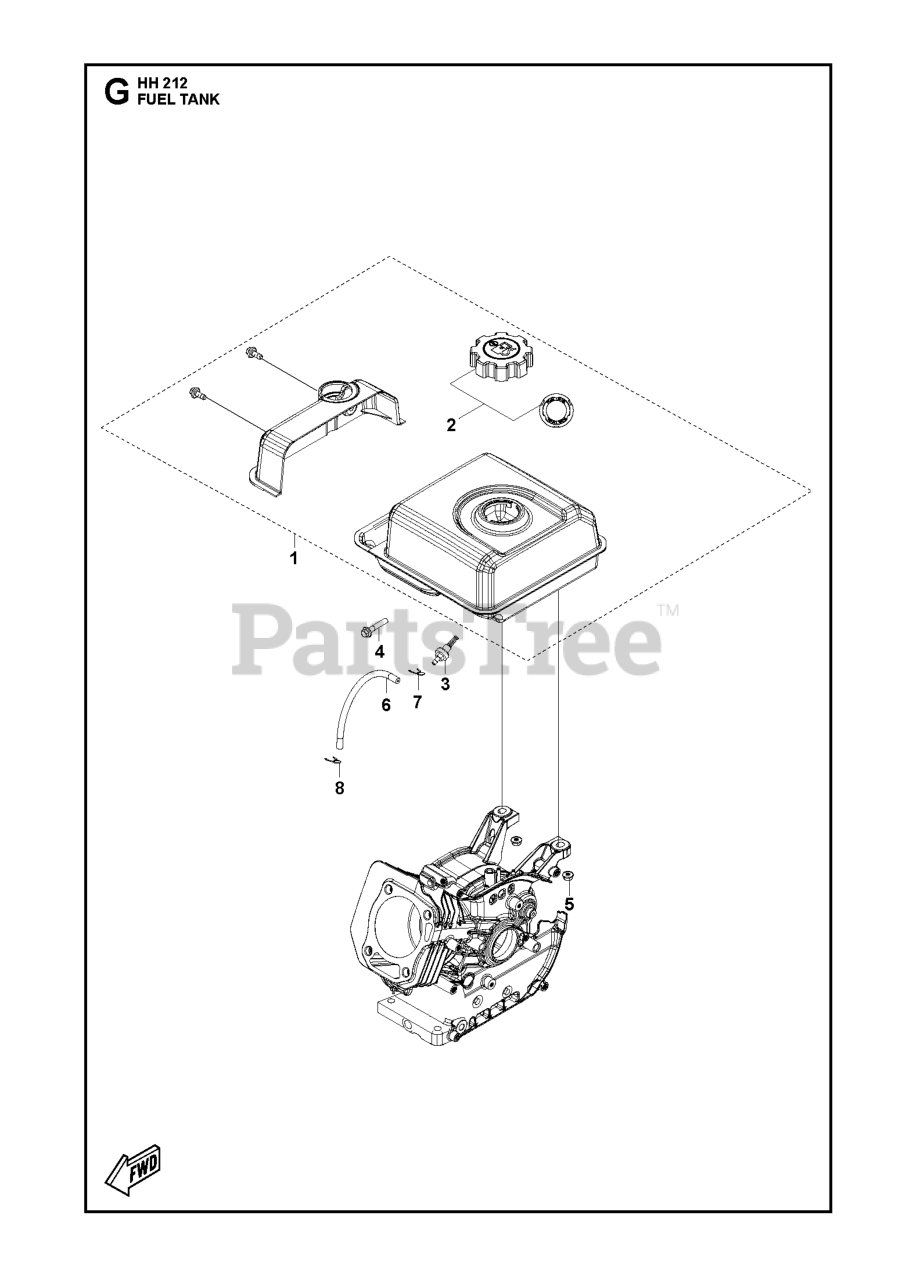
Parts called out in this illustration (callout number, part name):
1	FUEL TANK ASSY
2	FUEL CAP ASSY
3	FUEL GAUGE
4	BOLT
5	NUT
6	HOSE CARBURETTOR HOSE KIT
6	TUBE
7	CLIP HOSE CLIP
8	CLIP HOSE CLIP
